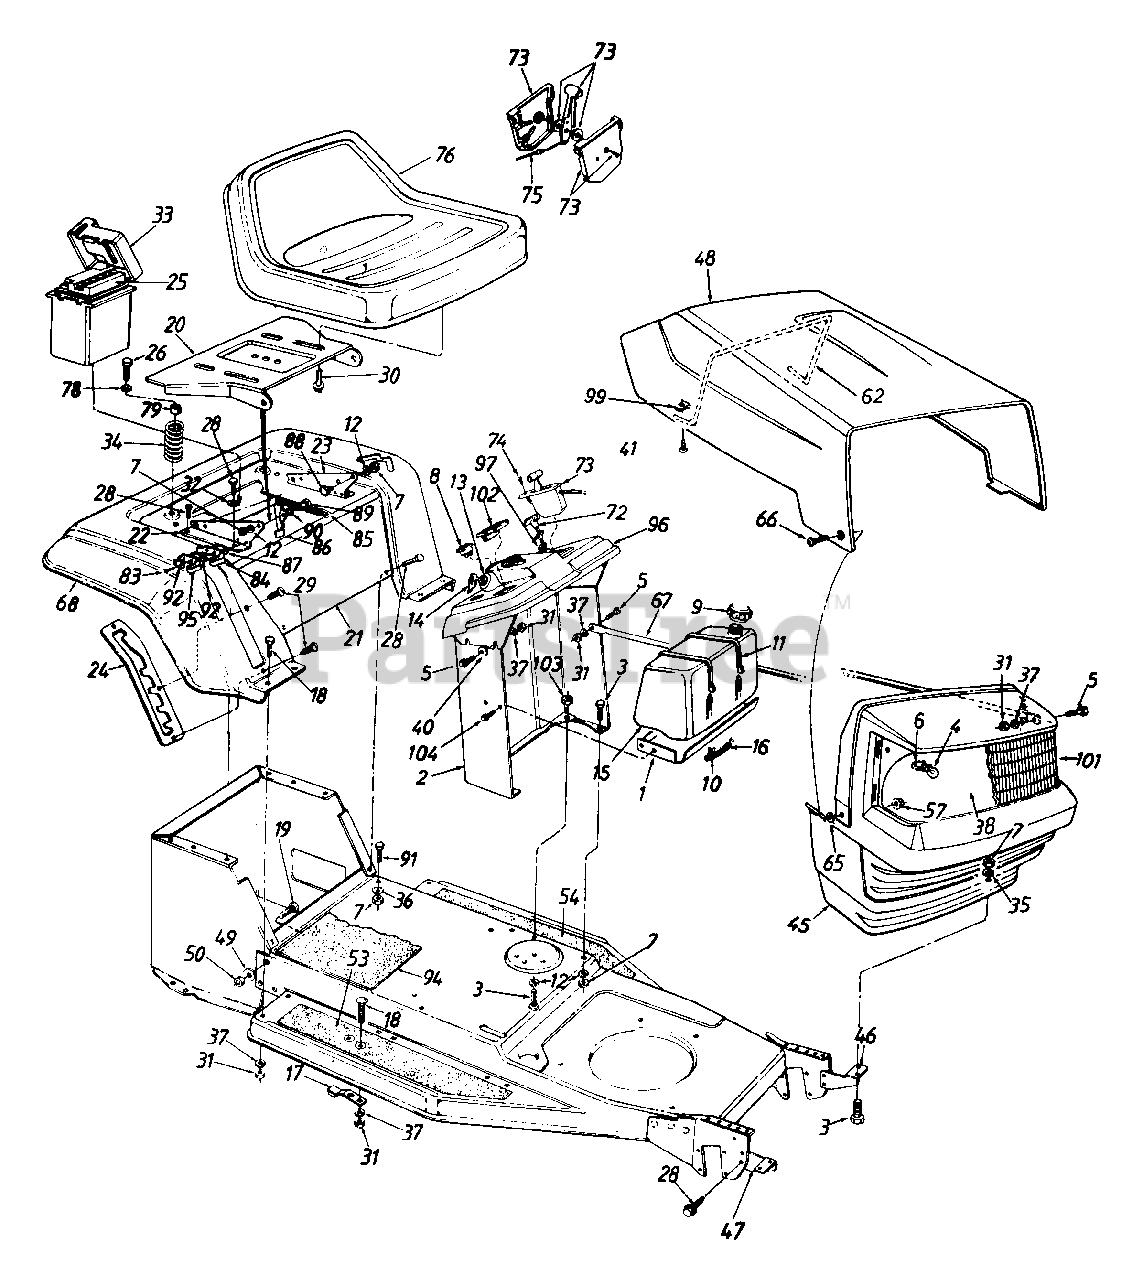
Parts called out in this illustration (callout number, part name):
3	Hex Bolt 5/16-18 x .75" Lg.
4	Bulb
5	Truss Mach. Scr. 1/4-20 x .75" Lg.
6	Socket
7	Hex Nut 5/16-18 Thd.
8	Light Switch
9	Gas Cap
10	Hose Clamp
11	Cable Tie
12	L-Wash. 5/16" I.D.
13	Ignition Switch
14	Ignition Key
15	Fuel Tank
16	Gas Line 15" Long
17	Blade Brake Ass'y.
18	Carriage Bolt 1/4-20 x .62"
19	Ribbed Neck Bolt 3/8-24 x .8"
20	Seat Pivot Brkt.
25	Battery
26	Hex Self-Tap Scr. 5/16-18 x 1.25" Lg.
28	Hex AB-Tap Scr. 5/16 x .75" Lg.
29	Torx Mach. AB-Tap Scr. 1/4 x .62" Lg.
30	Hex Self-Tap Scr. 3/8-16 x .75" Lg.
31	Hex Nut 1/4-20 Thd.
32	External L-Wash. 5/16" I.D.
33	Battery Box w/Cover
34	Compression Spring
35	Fl-Wash. .34" I.D. x 1" O.D.
36	Bell-Wash. 5/16" I.D.
37	L-Wash. 1/4" I.D.
38	Grille Reflector Label
40	Bell-Wash. .265" I.D. x .75"
41	Pan Hd. Scr. 10-24 x .75" Lg.
45	Grille (B&S)
46	Grille Mtg. Brkt. - L.H.
47	Grille Mtg. Brkt. - R.H.
48	Hood
49	L-Wash. 3/8" I.D. - H.D.
50	Hex L-Nut 3/8-24 Thd.
53	Foot Pad - R.H.
54	Foot Pad - L.H.
57	Lock Nut 1/4-28 Thd.
62	Hood Spring
65	Fl-Wash 28" I.D x .75" O.D.
66	Shld. Bolt
72	Choke Control
73	Throttle Control Box
74	Truss AB-Tap Scr. #10 x .5"
75	Throttle Wire (B&S)
75	Throttle Wire (Tec.)
76	Seat Assembly (Low Back)
76	Seat Assembly (Medium Back)
76	Seat Assembly (High Back)
76	Seat Assembly (Low Back - Yellow)
78	Fl-Wash. .344" I.D. x 88" O.D.
79	Bushing
83	Hex Tap Scr. #8 x .5" Lg.
84	Safety Switch (Seat)
85	Ext. Spring 5.31" Lg.
86	Seat Lift Brkt.
87	Insulator Boss Plate
88	Shld. Bolt .437" Dia. x .162" Lg.
89	Shld. Bolt .437" Dia. x .268" Lg.
90	Spr. Wash. .445" I.D x .75" O.D.
91	Hex Wash. Hd. Scr. 5/16-18 x .62" Lg.
92	Insulator Plate
94	Center Foot Pad
95	Safety Switch (Seat)
96	Dash Panel
97	Retainer Clip
99	Speed Nut
101	Lens
102	Ammeter
103	Hex Jam Nut 5/16-18 Thd.
104	Hex Wash. Hd. Tap Scr. 1/4-20 x .5" Lg.
